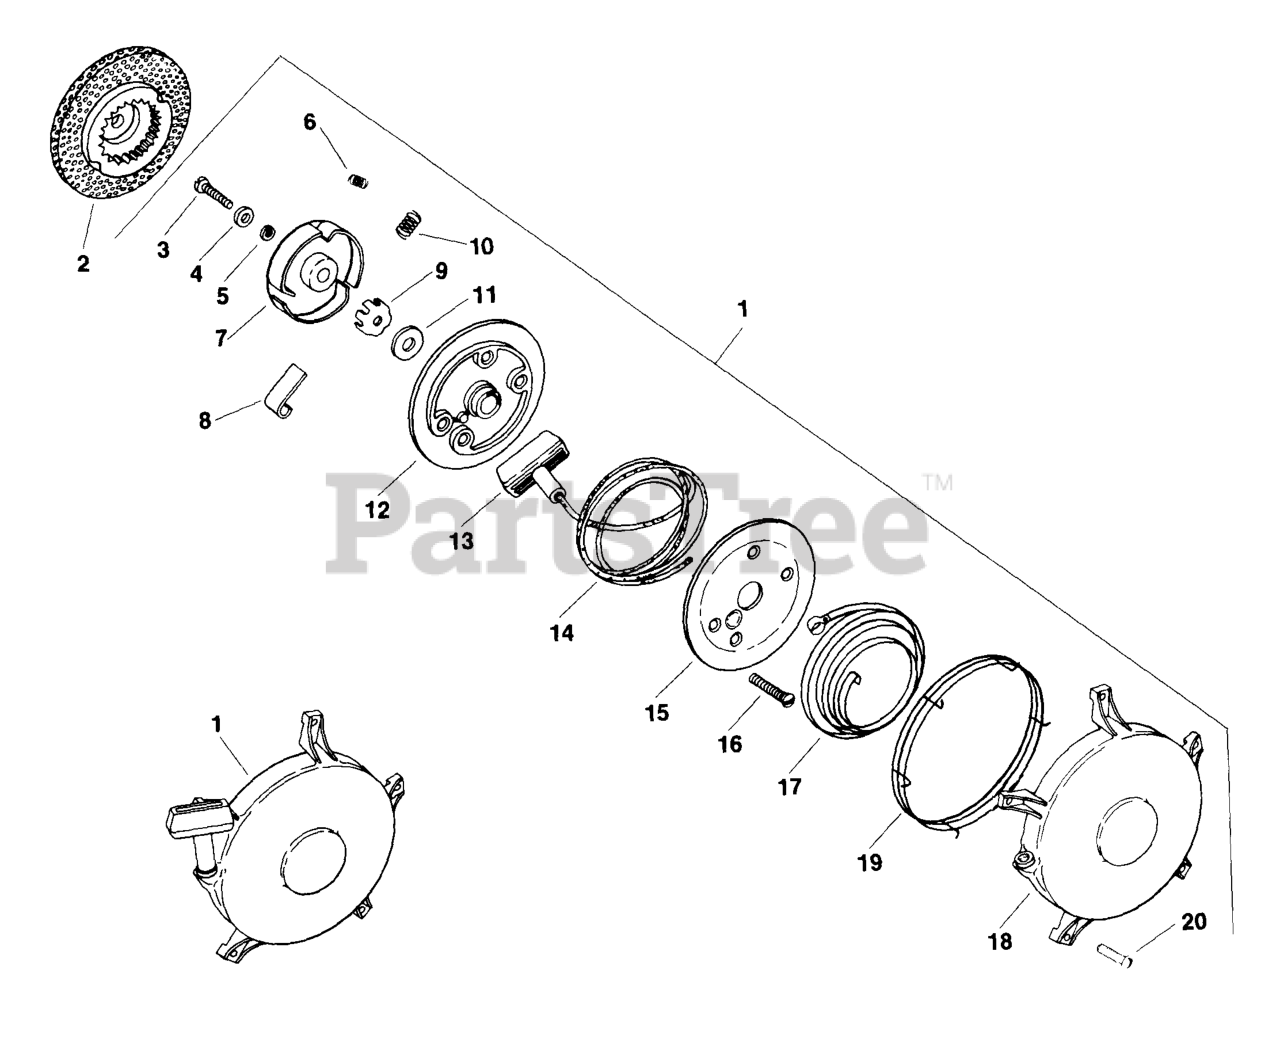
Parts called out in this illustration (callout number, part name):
1	KIT - USE 41 755 14
2	HUB/SCREEN ASSEMBLY (KM)-USE 41 071 08-S
2	CUP - DISCONTINUED
4	WASHER - DISCONTINUED
7	RETAINER
8	DOGS - DISCONTINUED
10	SPRING - DISCONTINUED
13	HANDLE - USE 25 166 01
18	HOUSING - DISCONTINUED
19	KIT - USE 41 755 14
20	SCREW
